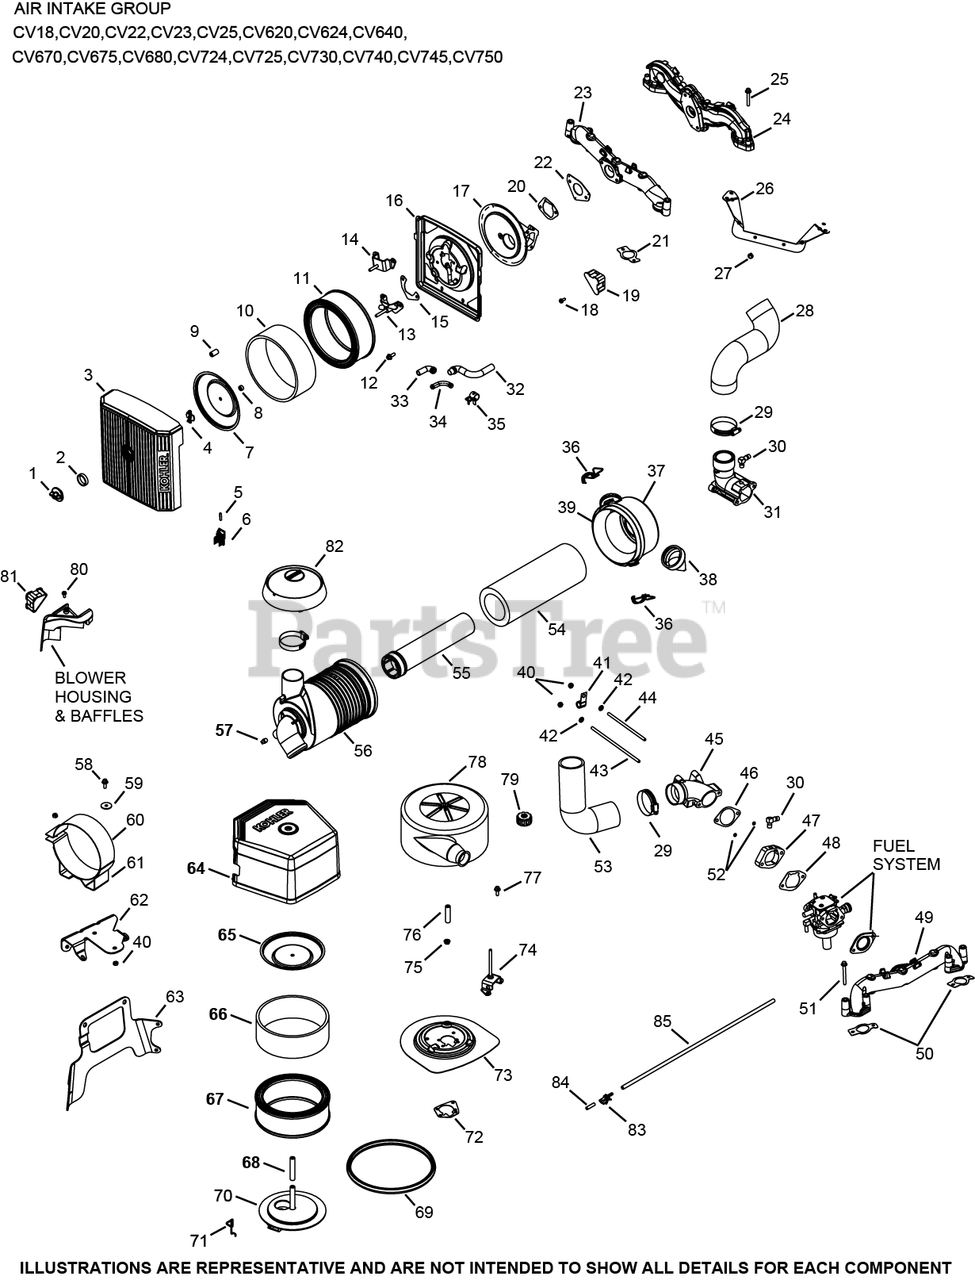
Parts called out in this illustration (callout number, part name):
1	KNOB, COVER
2	KIT, AIR CLEANER COVER
3	COVER, AIR CLEANER
4	NUT, WING
7	COVER, INNER AIR CLEANER
8	SEAL, INNER AIR CLEANER
10	ELEMENT, PRECLEANER (LOW)
11	ELEMENT, AIR CLEANER - Also available Retail Packaged 47 883 03-S1 Air Filter Kit
15	GASKET, FUEL SPITBACK CUP
20	GASKET, AIR CLEANER BASE
22	GASKET, CARBURETOR
26	BRACKET, AIR CLEANER BASE
75	NUT, FLG M6X1.0
83	CONNECTOR, EVAPORATIVE
84	CAP, MASKING
85	HOSE, EVAPORATIVE 20"
